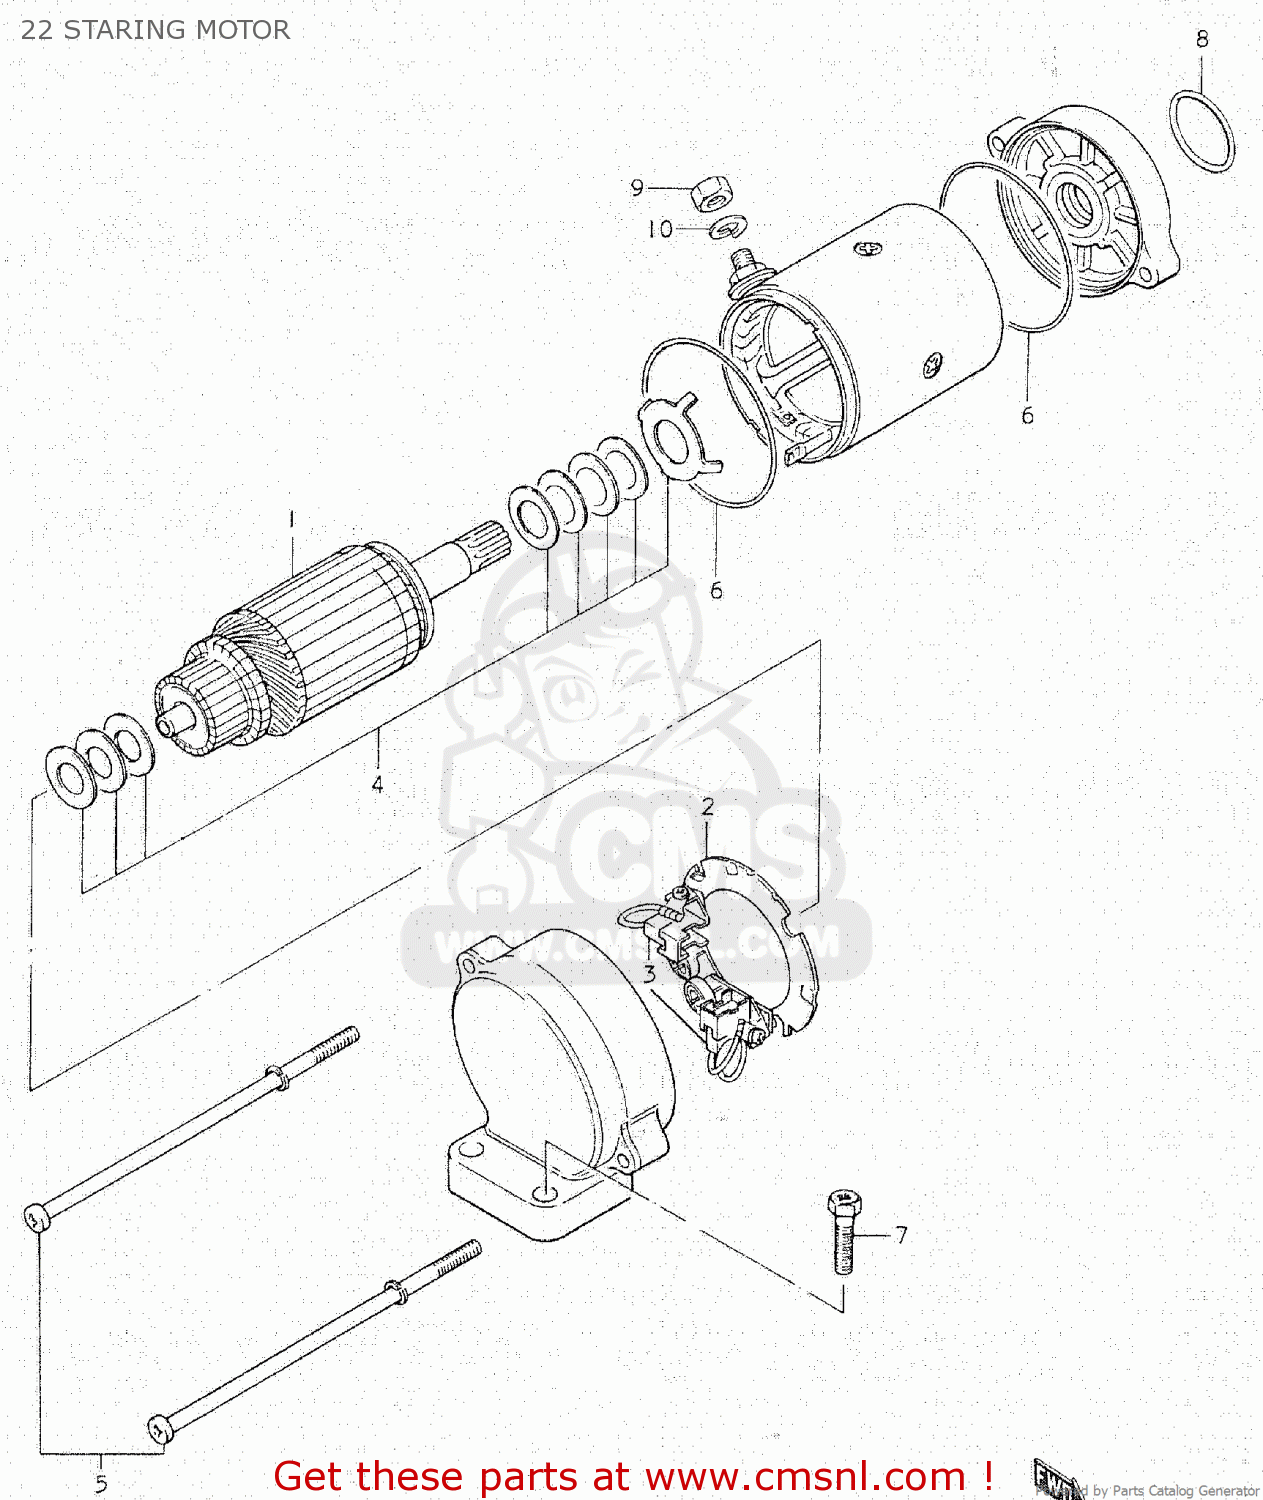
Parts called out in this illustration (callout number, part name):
1	ARMATURE
2	HOLDER ASSY
3	BRUSH SET
4	SHIM SET
5	BOLT,STARTING MOTOR HOUSING
6	O RING
7	SCREW
8	O RING(D:2,ID:24.5)
9	NUT 6MM
10	LOCK WASHER
